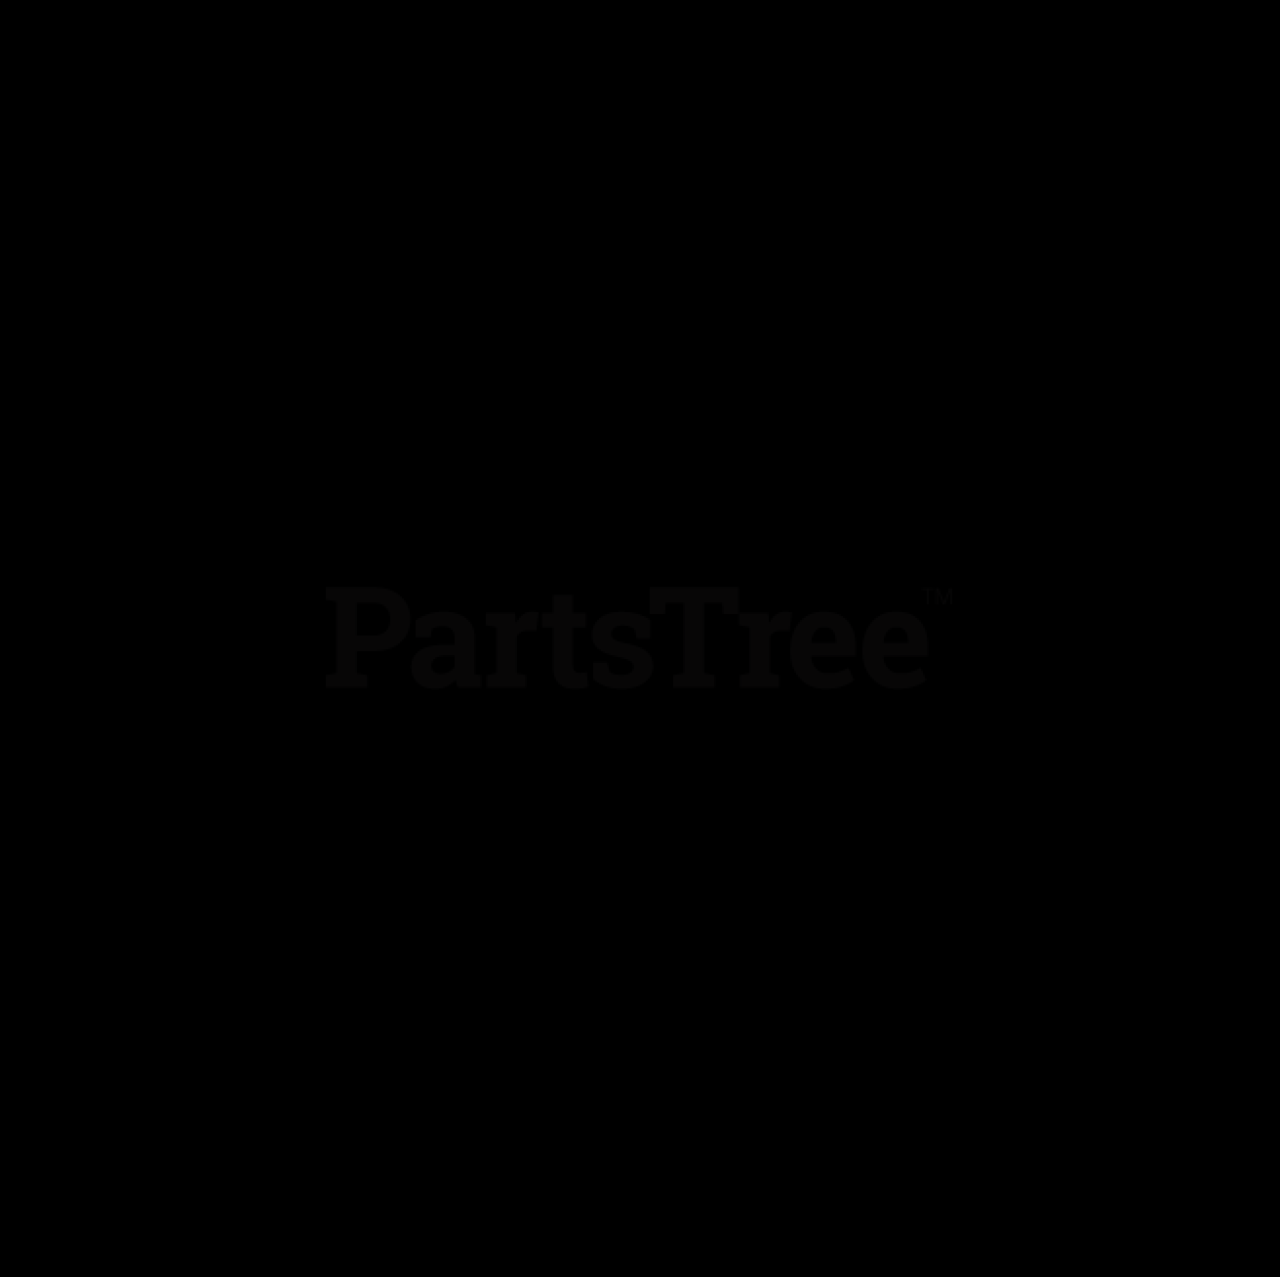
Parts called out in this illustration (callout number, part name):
1	Seat, with Seat Belt, Gray
2	Kit, Arm Rest – Plush, 5300, Pair
3	Kit, Retractable Safety Belt
4	Kit, Seat Cushion, Light Gray
5	Kit, Back Cushion, Light Gray
6	Kit, Seat Slide
7	Kit, Seat Knob
8	Kit, Spring and Saddle
9	Kit, Seat Back Panel
10	Nut, Locking Top Flange .31-18
11	Weldment, Hood Frame
12	Bushing, Flange .515 x .750 x .745 x 1.00
13	Bolt, Hex .25-20 x 1.00 Grade 5
14	Washer, Locking .25 x .062 Regular
15	Plate, Seat 200 XDZ with Latch
16	Rod, Seat Frame Pivot
17	Ring, Retaining External .500 x .050
18	Clip, Routing
19	Washer, Flat Steel .531 x 1.06 x .095
20	Tape, VHB
21	Nut, Hex .50-13
22	Nut, Locking Top Flange .50-13
23	Bolt, Hex .50-13 x 1.50
24	Washer, Flat Steel .344 x 1.125 x .135
25	Bushing, Polyliner .38 Snapin
26	Latch, Rotary-Push To Close
27	Rod, Seat Latch Release
28	Pin, Center .09 x .75 Extended Prong Square Cut
